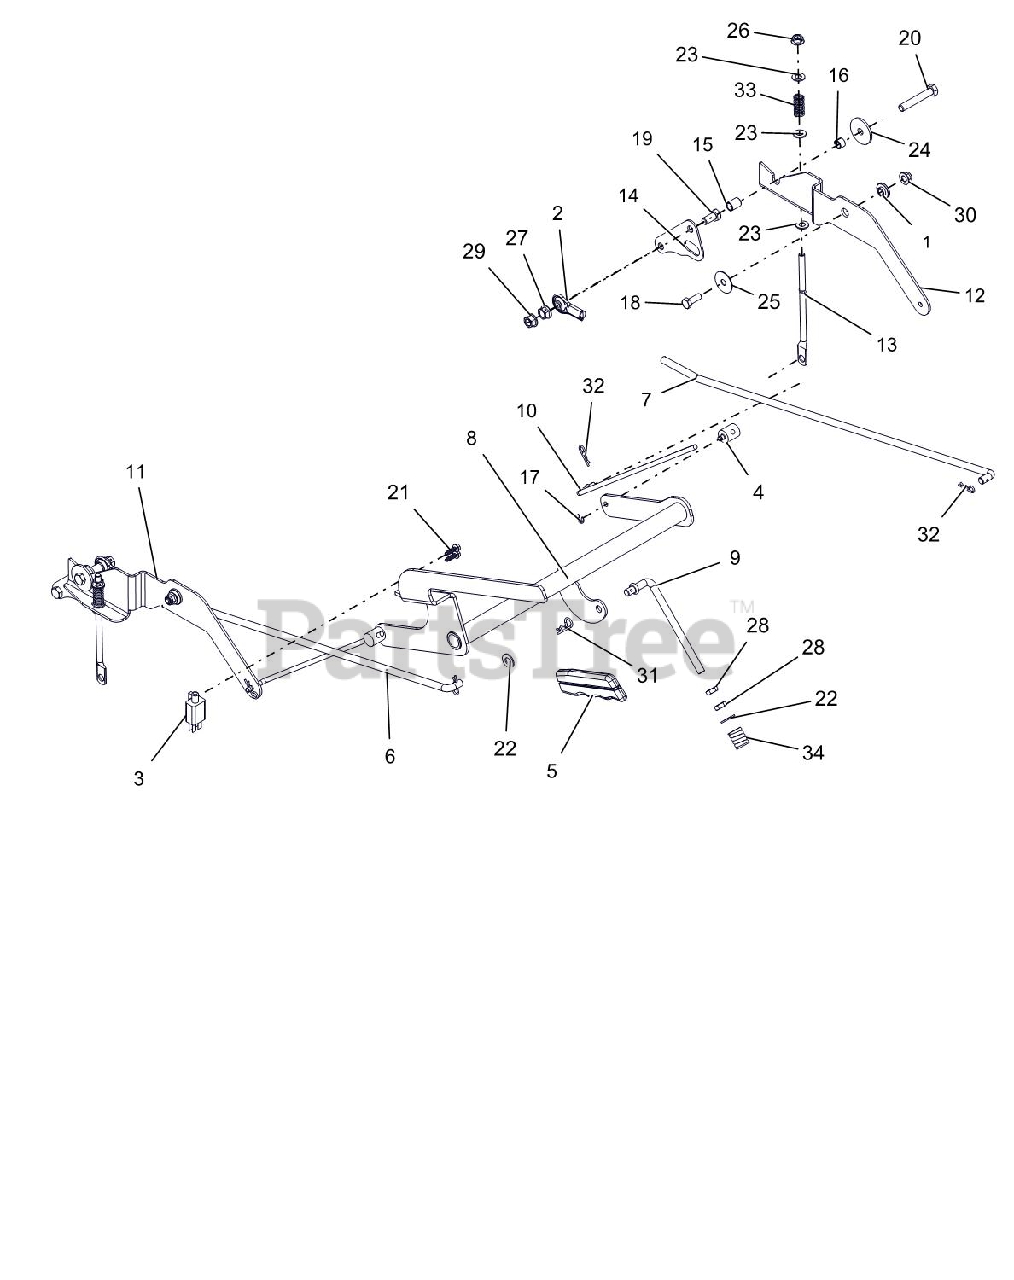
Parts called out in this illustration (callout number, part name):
1	BSHG, FLG .325X.499X.26X.88
2	ROD END, .38 RH
3	SWITCH- DOUBLE POLE N.O./N.O.
4	TRUNION, 1/4-20
5	GRIP, PARKING BRAKE (YELLOW)
6	STEERING, LINKAGE RH
7	STEERING, LINKAGE LH
8	WLDMT, BRAKE LEVER
9	LINK, OVER CENTER, PARKING BRK
10	ROD, PARK BRAKE
11	INTERLOCK, RH BRAKE LINK
12	INTERLOCK, LH BRAKE LINK
13	LINK, TRANSAXLE BRAKE
14	PLATE, TRANSAXLE ADAPTOR
15	SPCR, SLV .385X.500X.652
16	SPCR, SLV .385X.500X.350
17	RG-RTNG-EXT .250X.025
18	BOLT-HEX.31-18X.875 YWZC GR5
19	@BLT-HEX .38-16X.75 GR5 YWZC
20	@BLT-HEX .38-16X2.25 GR5 YWZC
21	SCR-TAP #12X.75 BOSS INDHXHD
22	@WSHR-FL-STL.406X.812X.065 YWZ
23	@WSHR-FL-STL.344X.688X.065YWZC
24	WSHR-FL-STL .380X1.50X.125YWZC
25	WSHR-FL-STL .347X1.254X.048YWZ
26	@NUT-LK-CTR-FLG .31-18 YZ GR F
27	NUT-LK-CTR-FLG .38-16 YWZC
28	NUT-HEX-JAM .375-16 YWZC
29	@NUT-LK-TOP-FLG .38-16 YWZC
30	@NUT-LK-NYL-FLG .31-18 YWZC
31	PIN-HAIR CTR .09 X 1.50 YWZC
32	PIN-HAIR INT .08X.18X1.18 YWZC
33	SPRING, COMPRESSION
34	SG-COMP .187X.56X1.62
